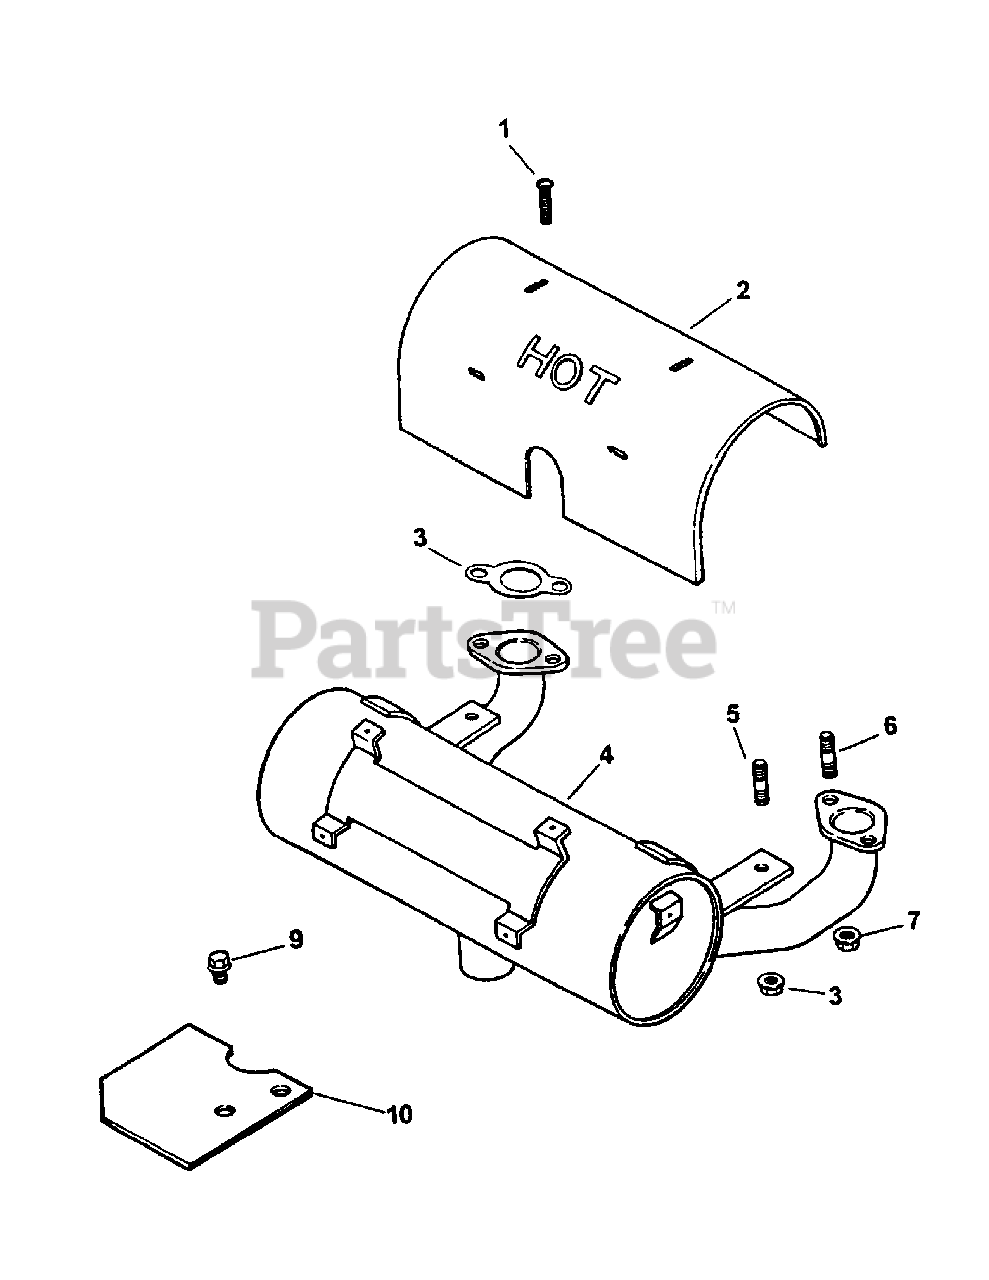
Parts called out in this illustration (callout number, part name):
1	Screw, Sems Drill 8-18 x 9/16"
2	Duct, Heat Shield
3	Gasket, Exhaust
4	Muffler, Center Outlet
6	Stud
7	Nut, Muffler Mounting
8	Nut, Hex Flange
9	Screw, Hex Flange
10	Deflector, Heat
